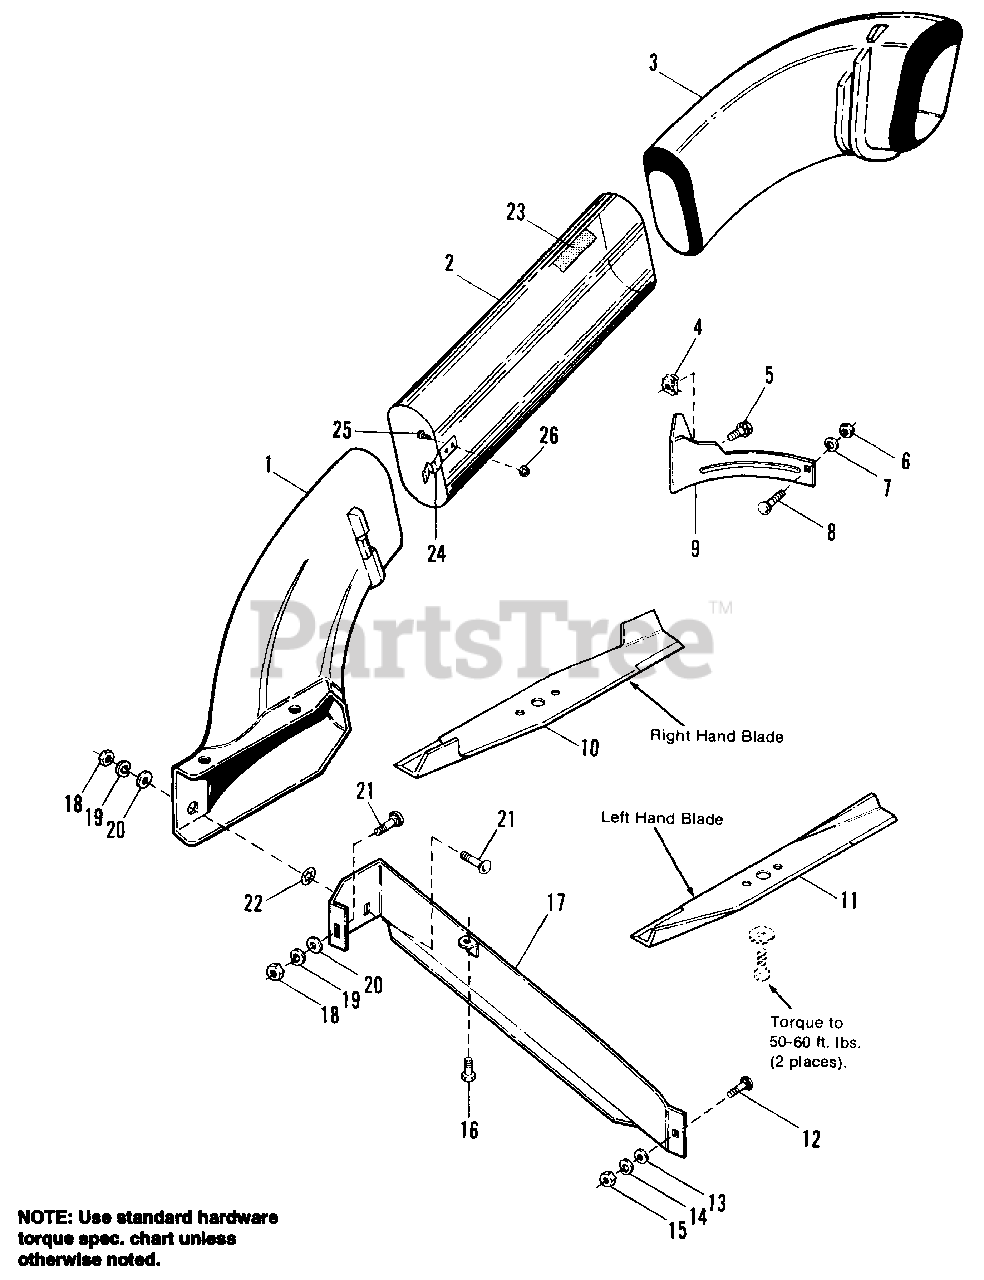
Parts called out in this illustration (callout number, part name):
2	TUBE ASSY.
4	NUT, Retainer, 1/4-20
5	SCREW, Whizlock, 1/4-20 x 1/2
6	NUT, Hex, 1/4-20
7	LOCKWASHER, 1/4
8	BOLT, Carriage, 1/4-20 x 5/8
9	BAFFLE, Deflector Side
10	BLADE, R.H.
11	BLADE, L.H.
12	BOLT, Carriage, 5/16-18 x 7/8
13	WASHER, 1/4
14	LOCKWASHER, 5/16
15	NUT, Hex, 5/16-18
16	SCREW, Taptite, 5/16-18 x 1/2
17	BAFFLE ASSY., Discharge
18	NUT, Hex, 3/8-16
19	LOCKWASHER, 3/8
20	WASHER, 3/8
21	BOLT, Carriage, 3/8-16 x 3/4
22	NUT, Push-On
23	DECAL, Cleaning Instructions
24	SPRING, Retaining
25	SCREW, Truss, Phil. Hd., #10-32 x 1/2
26	NUT, Hex Washer, #10-32
